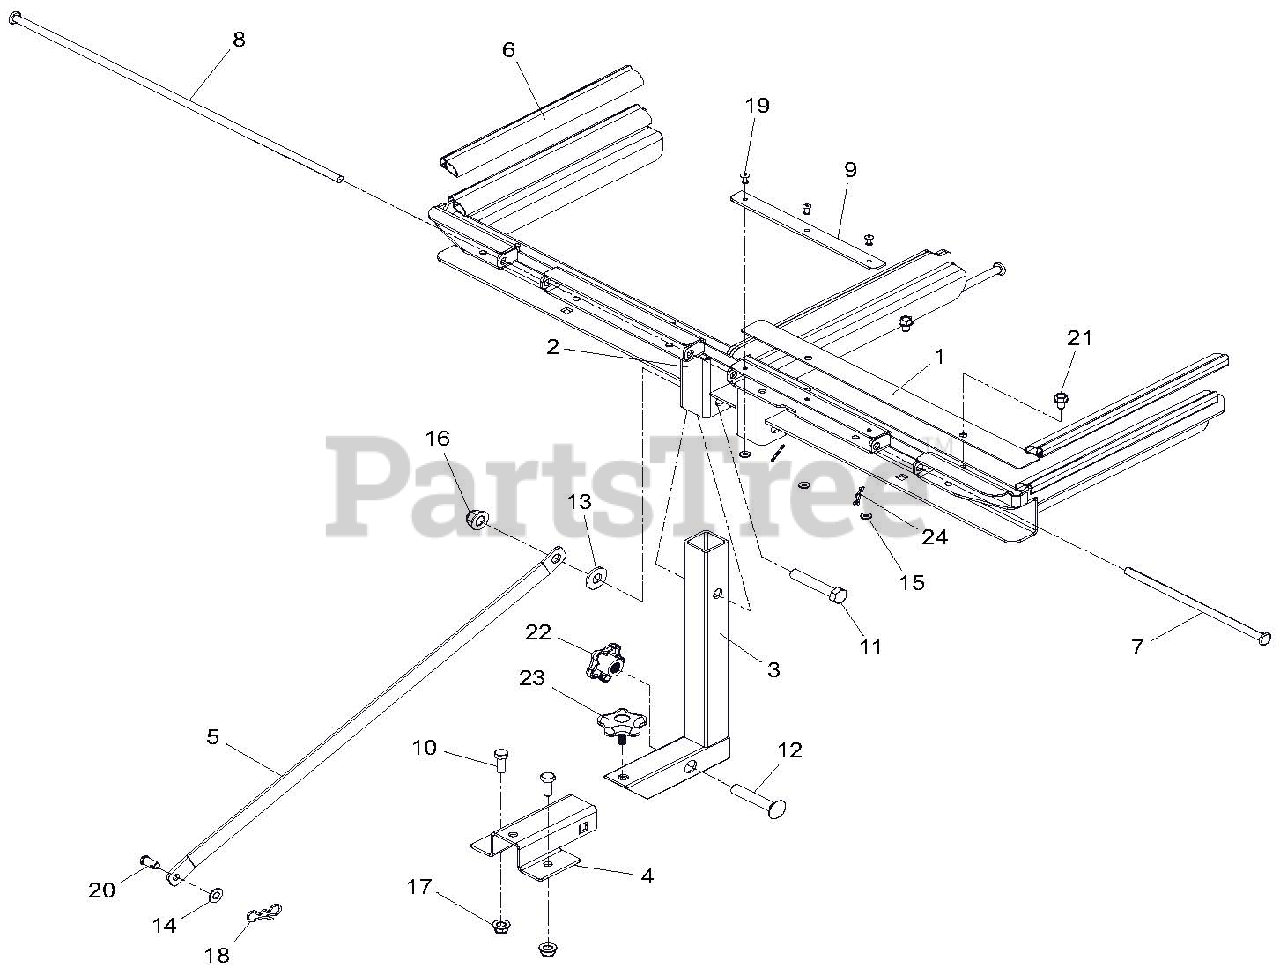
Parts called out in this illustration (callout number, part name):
1	OVERLAP PLATE, BAGGER FRAME
2	ASM, BAGGER FRAME UPPER
3	BRKT, RECEIVER SLEEVE INSERT
4	BRKT, RECEIVER LOWER
5	BRKT, BAG FRAME SUPPORT BAR
6	SEAL, BULB
7	PIN, BAGGER HINGE
8	PIN, BAGGER HINGE
9	SEAL, HINGE
10	BOLT-HEX-Gr5-UNC-YWZC
11	BOLT-HEX-Gr5-UNC-YWZC
12	BLT-RDHDSQNK .50-13X2.75 YG5
13	WSHR-FL-STL .531X1.250X.100 YWZC
14	WSHR-FL-STL.406X.812X.065 YWZ
15	WSHR-FL-STL.219X.500X.049 YWZC
16	NUT-LK-NYL-FLG .50-13 YWZC
17	NUT-LK-NYL-FLG .38-16 YWZC
18	PIN, BOWTIE LOCKING .091X1.875
19	RVT-POP .187x.375
20	PIN-CLEV .38X.75 YWZC
21	SCR-TAP .31-18X.50 HWH TR YWZ
22	KNOB, WING
23	KNOB, WING STUDDED
24	PIN-HAIR, ENDRIES #25 YWZC
